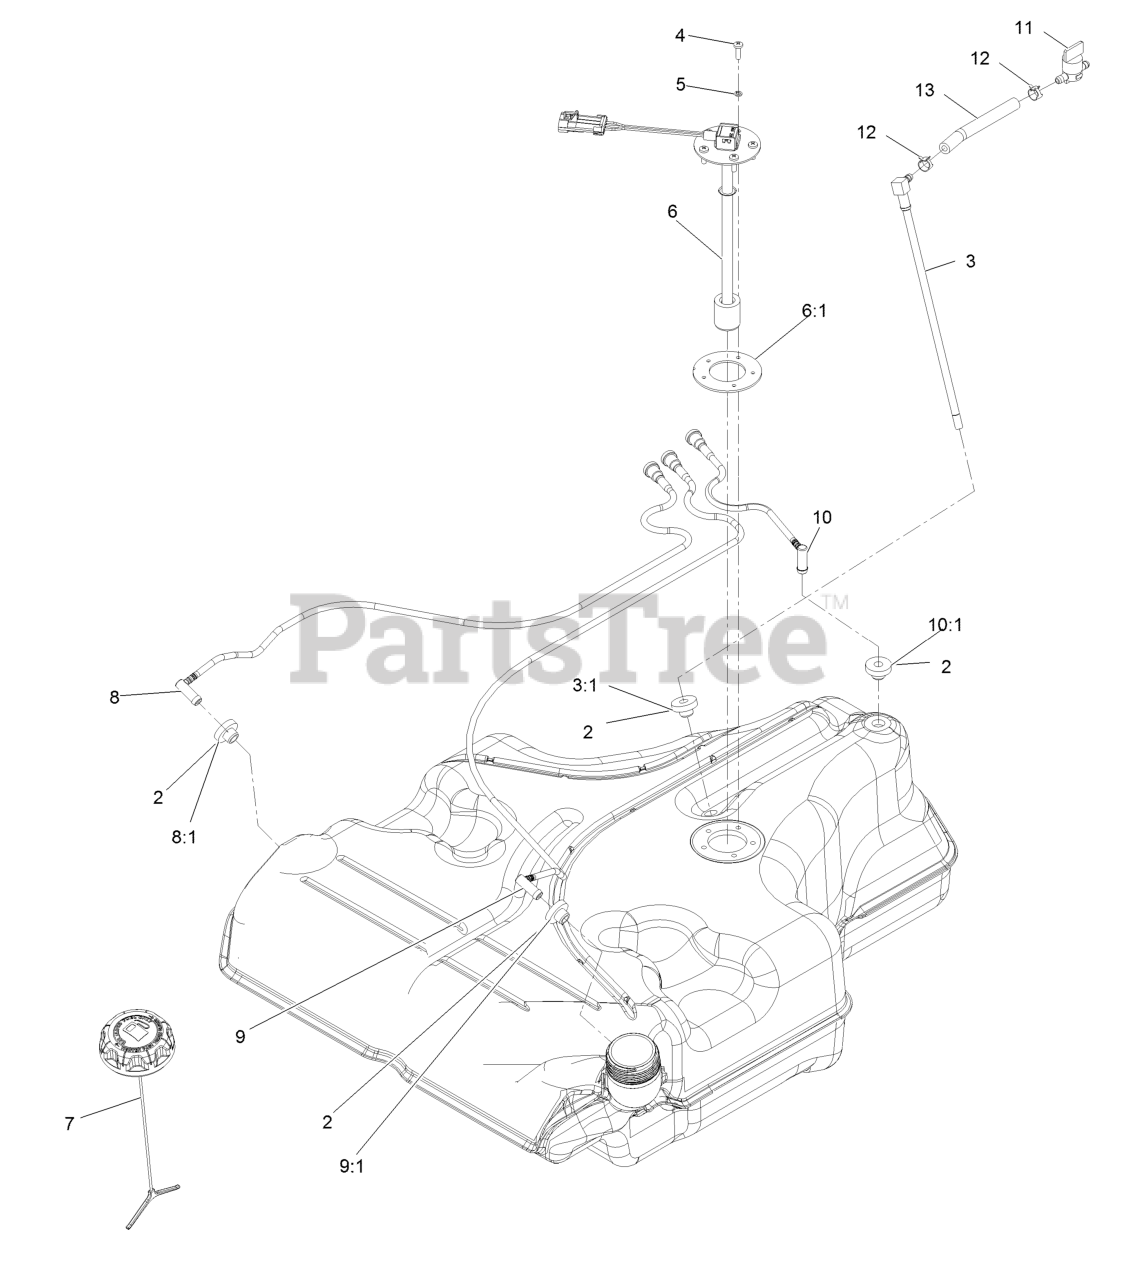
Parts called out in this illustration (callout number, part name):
2	Bushing
3	Fuel Line Kit (With Grommet)
3:1	Bushing
4	Screw-PPH #10-24 X 5/8
5	Washer-Lock 3/16
6	Sender-Level, Fuel (W/Gasket)
6:1	Gasket-Sender
7	Cap-Fuel, Ratcheting
8	RH Vent Line Kit (With Grommet)
8:1	Bushing
9	LH Vent Line Kit (With Grommet)
9:1	Bushing
10	Rear Vent Line Kit (With Grommet)
10:1	Bushing
11	Valve-Fuel
12	Clamp-Hose
13	Hose-Fuel
